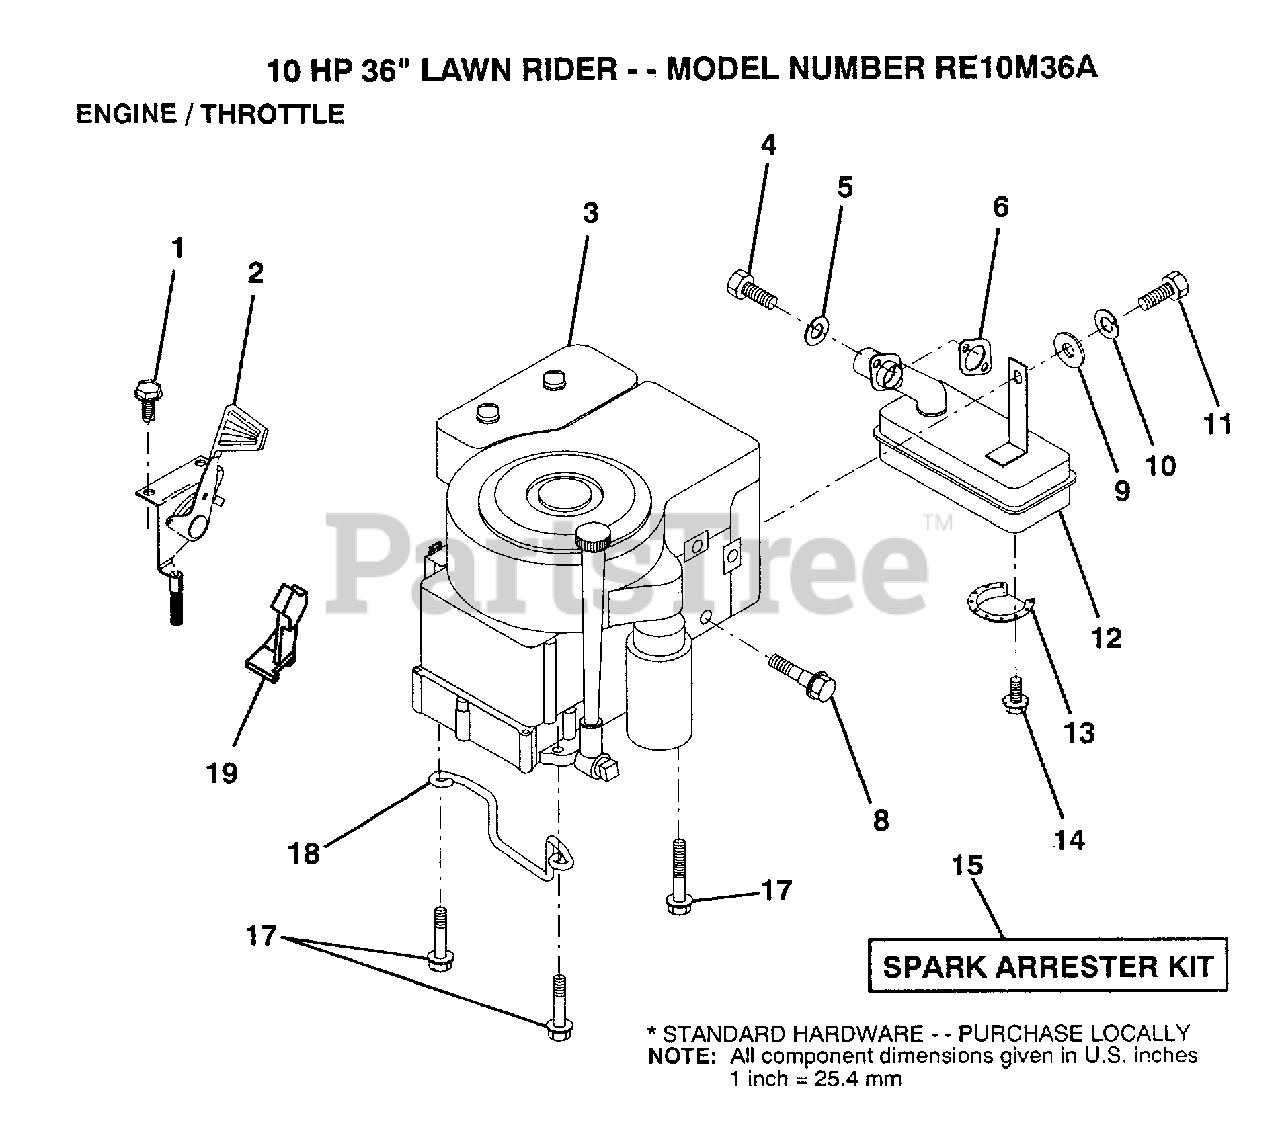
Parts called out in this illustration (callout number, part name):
1	SCREW
4	SCREW
5	LOCKWASHER
8	BOLT T
10	LOCKWASHER
13	DEFLECTOR.222573
17	SCREW LT
18	"KEEPER,DR BELT GR"
19	"STEP,CHOKE"
